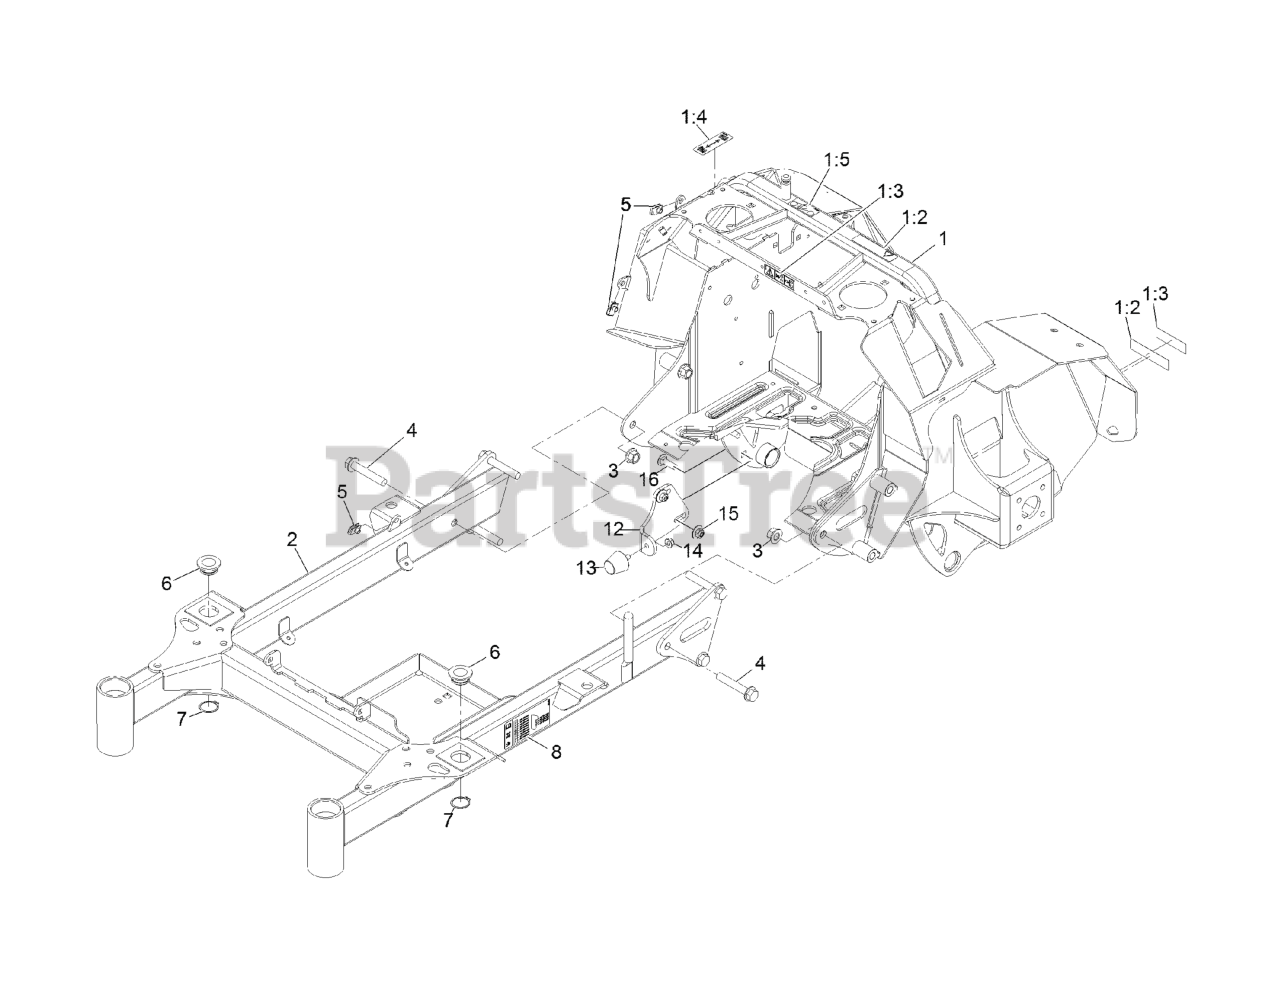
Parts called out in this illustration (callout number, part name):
1	ASM-FRAME
1:2	DECAL-WARNING
1:3	DECAL, COVER MISSING
1:4	DECAL-BRAKE, PARKING
1:5	DECAL-BELT ROUTING HYD
2	ASM-FRONT FRAME 44
3	Nut-Lock 1/2-13
4	SCREW-HF
6	BUSHING-DECK
7	RING-RETAINING
8	DECAL-HEIGHT OF CUT SM
12	BRACKET-BUMPER
13	BUMPER-RUBBER
14	NUT-HF, NI
15	Nut-Nyloc 3/8-16 Flg
16	BOLT-CARR
